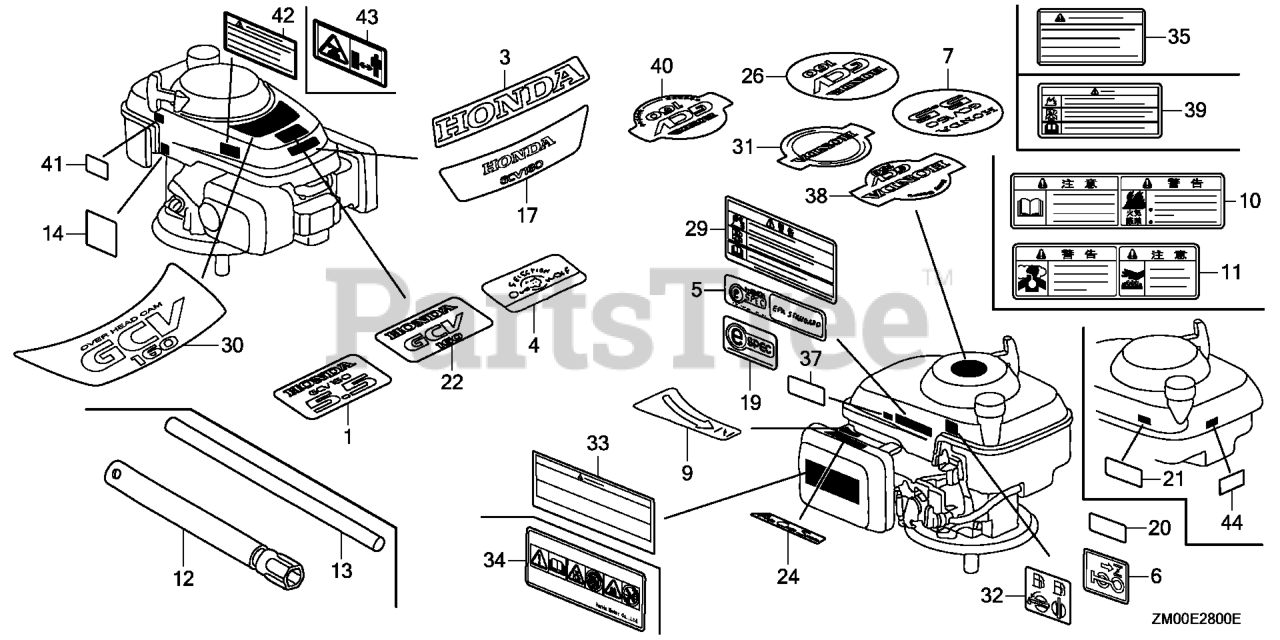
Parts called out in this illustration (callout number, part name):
30	MARK, EMBLEM *186C* (SPECIFIED RED)
31	MARK, RECOIL COVER
32	MARK, FUEL PETCOCK CAUTION
33	MARK, OPERATOR CAUTION (ENGLISH)
34	MARK, OPERATOR CAUTION
42	MARK, EX. CAUTION (ENGLISH)
43	MARK, EX. CAUTION (PICTOGRAPH)
